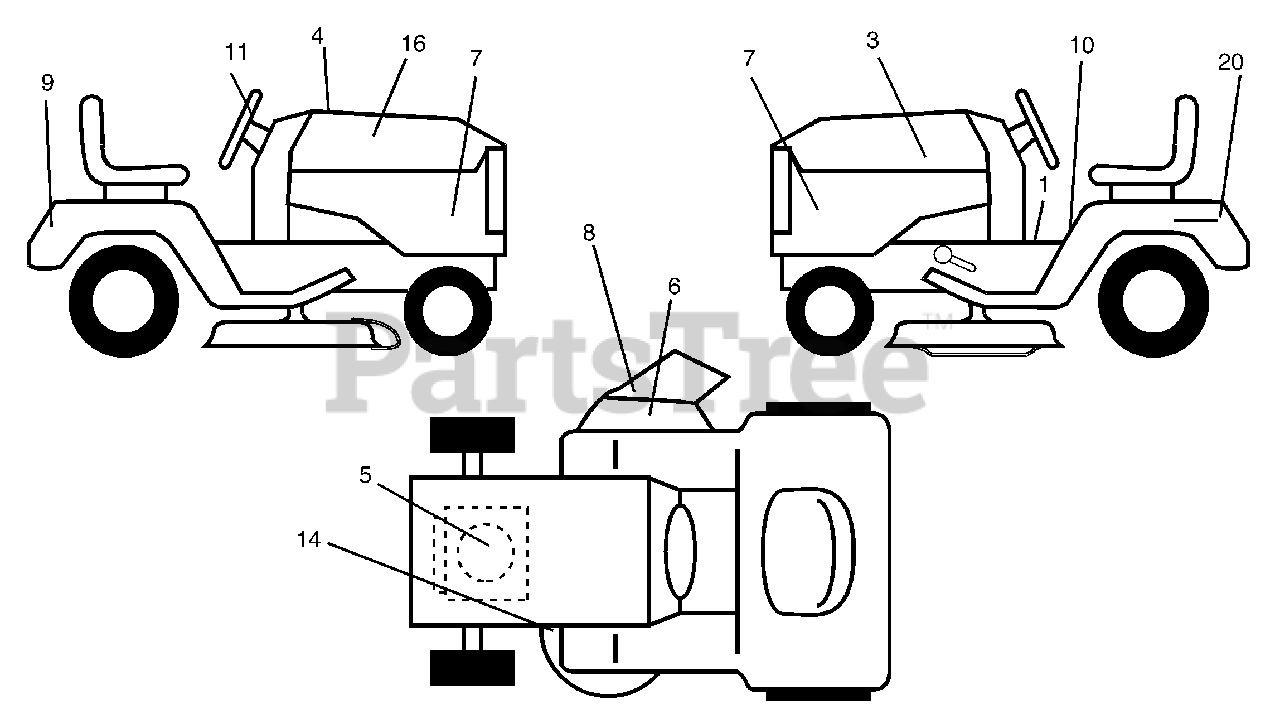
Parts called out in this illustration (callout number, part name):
1	Decal Oper
3	Decal Hood LH
4	Decal Replace
5	Decal HP Engine
6	Decal Deck "B" 42"
7	Decal Side Panel
8	Decal Warning Mult-Language
9	Decal Fender Logo
10	Decal Fender Danger E/F
11	Decal Ins Strg Whl
14	Decal V-Belt Schematic
16	Decal Hood Rh
20	Decal Bat Dan/Psn
